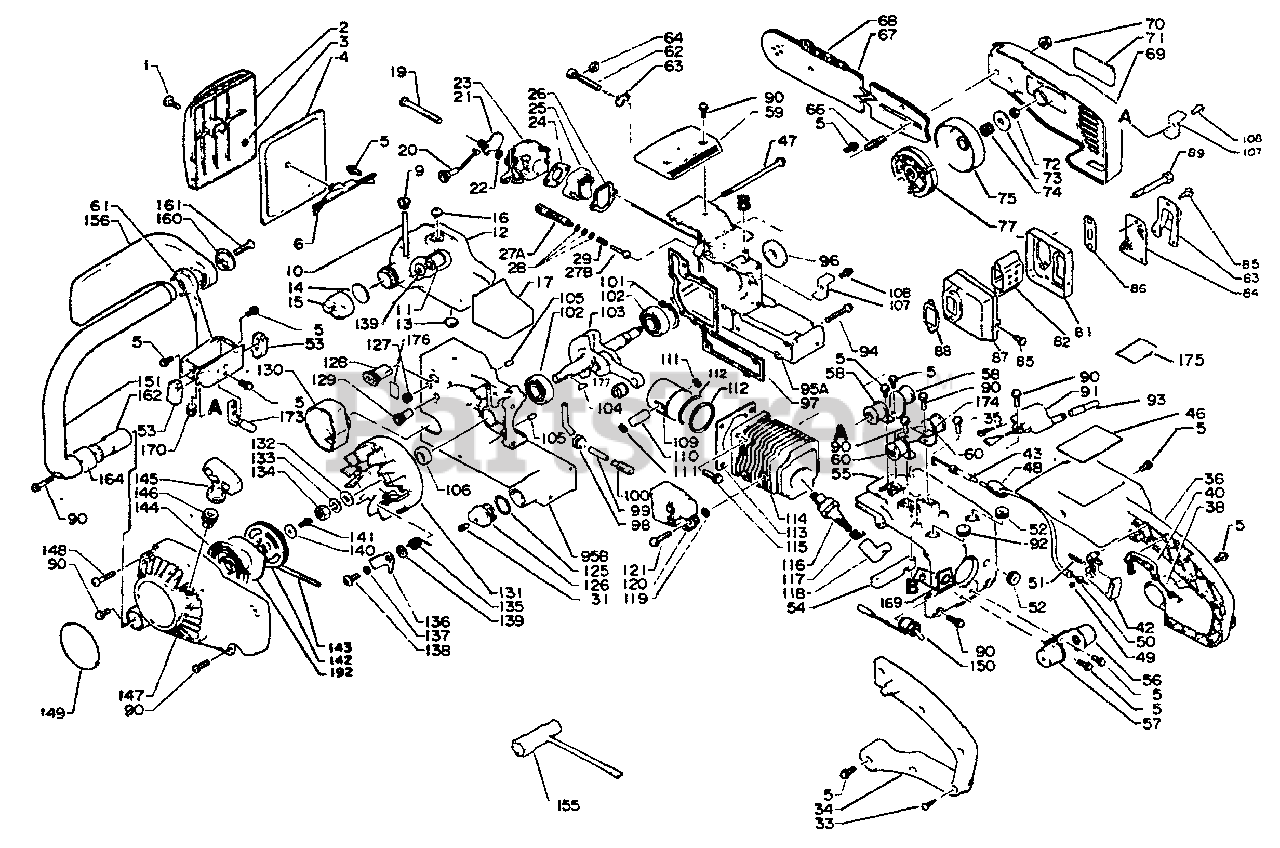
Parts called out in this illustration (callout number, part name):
1	THUMBSCREW
2	COVER, AIR FILTER
3	RING, RETAINING - 4
4	FILTER, AIR
5	SCREW - 4X10
6	BRACKET, AIR CLEANER
9	FILTER, FUEL
10	FUEL PIPE KIT
11	FILTER, FUEL
12	TANK, FUEL
14	GASKET, CAP
15	CAP ASSY
16	VENT
17	CUSHION
19	SCREW - 5X55
20	ROD, CHOKE
21	SHUTTER, CHOKE
22	WASHER
23	CARBURETOR C1S-K1C
24	GASKET, INTAKE
25	INSULATOR
26	GASKET, INTAKE
27	AUTO-OILER ASSY
27A	AUTO-OILER ASSY
27B	AUTO-OILER ASSY
28	O-RING - 5
31	VENT, TANK
33	SCREW - 4X16 -- TAPPING
34	HANDLE - REAR
36	HANDLE - REAR
38	SPRING, LOCKOUT LEVER
40	LOCKOUT, THROTTLE
42	TRIGGER, THROTTLE
43	CABLE, THROTTLE
46	LABEL - MODEL
48	GROMMET
49	SCREW - SET
51	SPRING, TRIGGER
54	SPACER
55	COVER, ENGINE
56	CUSHION
57	CUSHION
59	COVER, INTAKE
60	Cushion (U)
61	BRACKET, HANDLE - UPPER
62	SCREW, TENSIONER
63	TENSIONER, CHAIN
66	STUD, GUIDE BAR
67	GUIDE BAR
68	CHAIN, SAW
69	GUARD, SPROCKET
70	NUT - 6 -- FLANGE
72	LOCKNUT - 6
74	BEARING, NEEDLE
75	DRUM, CLUTCH
77	CLUTCH ASSY
81	LID, MUFFLER
82	BAFFLE, MUFFLER
83	GUIDE, EXHAUST
84	SCREEN, SPARK ARRESTOR
85	SCREW - 4X8
86	WASHER - 5
87	GUIDE, EXHAUST
88	GASKET, EXHAUST
90	SCREW - 4X16
91	COIL, IGNITION
93	TUBE
94	SCREW - 4X30
95	CRANKCASE KIT
95A	CRANKCASE KIT
95B	CRANKCASE KIT
96	SEAL, OIL
97	GASKET, CRANKCASE
98	GROMMET
99	PIPE - OIL
100	FILTER, OIL
101	RING, RETAINING - 32
102	BEARING, BALL - 6201
103	CRANKSHAFT ASSY
105	PIN - LOCATING
106	SEAL, OIL
107	CATCHER, CHAIN
108	SCREW - 5X10
109	PISTON
110	PIN, PISTON
111	RING, RETAINING
112	RING, PISTON
113	GASKET, CYLINDER
114	CYLINDER
115	SCREW - 5X20
116	SPARK PLUG -- CJ-8Y
117	TERMINAL, SPARK PLUG CAP
118	CAP, SPARK PLUG
119	SPACER
120	COIL, IGNITION
121	SCREW - 5X22
125	O-RING - 16
126	CAP ASSY
128	GROMMET
129	GROMMET
130	SEAL
131	FLYWHEEL
132	WASHER - 8
133	LOCKWASHER - 8
135	SPRING, RETURN
136	PAWL, STARTER
138	SCREW
139	WASHER - 5
140	WASHER - 4
141	SCREW - 4X10
142	REEL, ROPE
143	ROPE, STARTER - 3.5X850
144	SPRING, REWIND
145	GRIP, STARTER
146	GUIDE, ROPE
147	CASE, STARTER
148	SCREW - 4X25
149	LABEL - ECHO
150	SWITCH, IGNITION
151	HANDLE - FRONT
155	T-WRENCH - 10X19mm
160	Holder, guard
161	SCREW - 5X25
162	CUSHION
169	PLATE
170	CUSHION
175	LABEL - NOISE
176	LABEL - CHOKE
177	BEARING, NEEDLE
192	PLATE, STARTER
